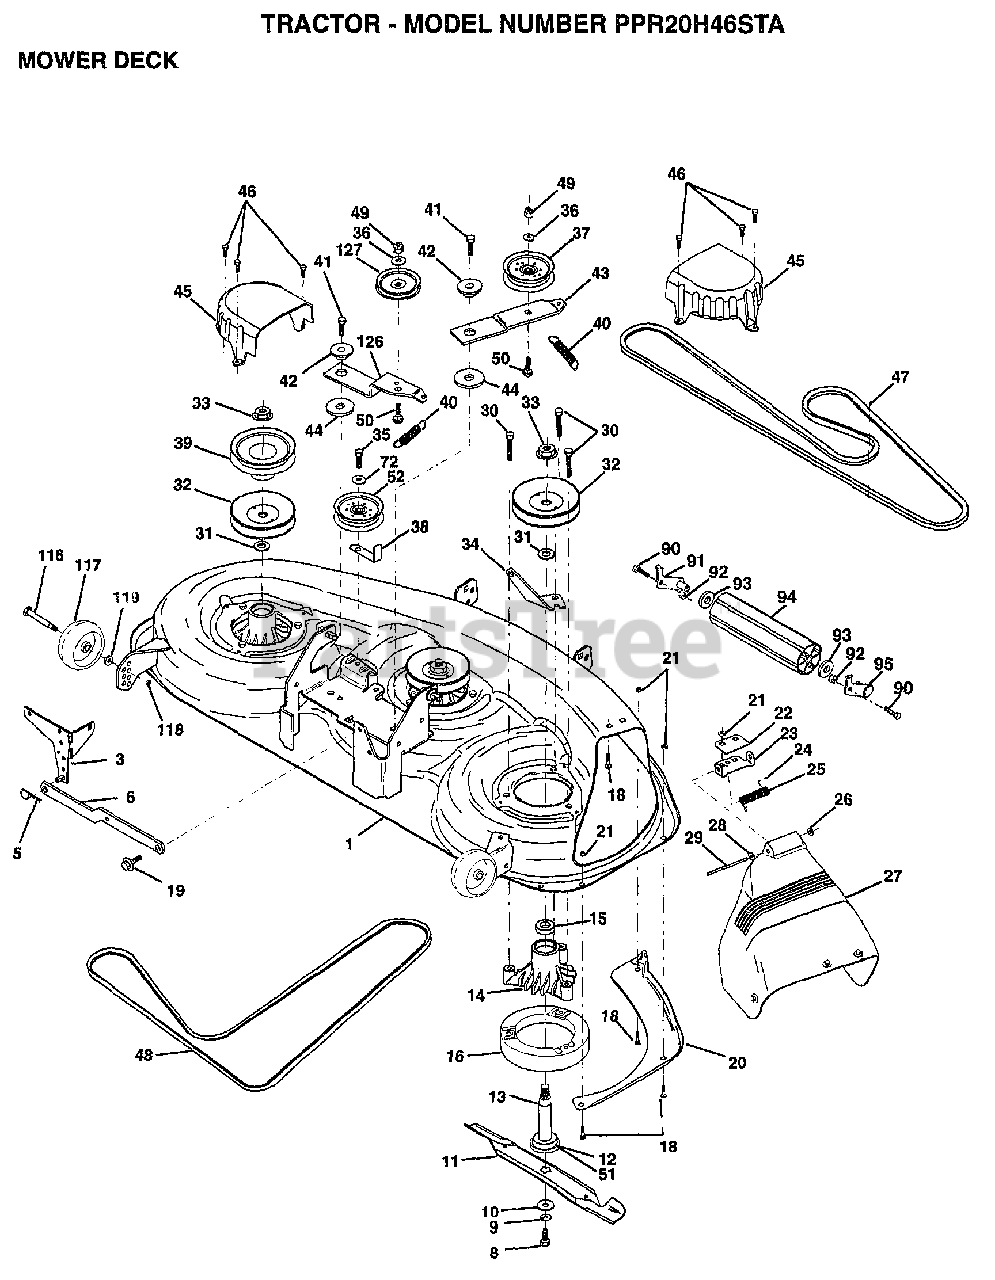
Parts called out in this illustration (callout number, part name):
1	"MOWER ASM 46"""
3	BRKT.ASM.SW.44/50
8	BLADE BOLT
10	WASHER.HARD.BLADE
11	"BLADE.HIGHLIFT46"""
12	BEARING.BALL
13	SHAFT.ASM.W/BRNG
14	HOUSING.MAND.44.V
15	BEARING
16	STRIPPER RND MWR
18	BOLT
19	BOLT SHD 5/16-18
20	BAFFFLE.VORTEX.46
22	STIFFENER BRKT
23	DEFLECTOR BRKT
24	CAP-SLEEVE LT
26	NUT PUSH M
27	SHIELD DEFLECTOR
28	WASHER
29	HINGE ROD
30	"SCREW-THD ROLL,WA"
31	WASHER
32	PULLEY.MAND.36/46
34	ANCHOR.SPRING.46
35	SCREW LT
36	WASHER
37	FLAT IDLER PULLEY
38	"KEEPER BELT,IDLER"
39	PULLEY.DRV.DCK.46
40	"SPRING.SEC.44""VEN"
41	SCREW
42	SPACER RETAINER
43	ARM.IDLER.DECK.46
44	HARDENED WASHER
45	COVER.MANDREL.46
46	SCREW.1/4-20X5/8
47	BELT-V.SEC.46.KEL
48	BELT.MWR.PRM.85.4
50	BOLT.3/8-16X1.50
51	WASHER.FELT.
52	"PULLEY IDLER,FLAT"
72	WASHER HYT
90	BOLT
92	NUT
93	WASHER
116	BOLT M
117	WHEEL.GUAGE
118	LOCKNUT
119	WASHER
126	ARM.IDLER.PRIM.46
127	PULLEY.IDLER.4.25
